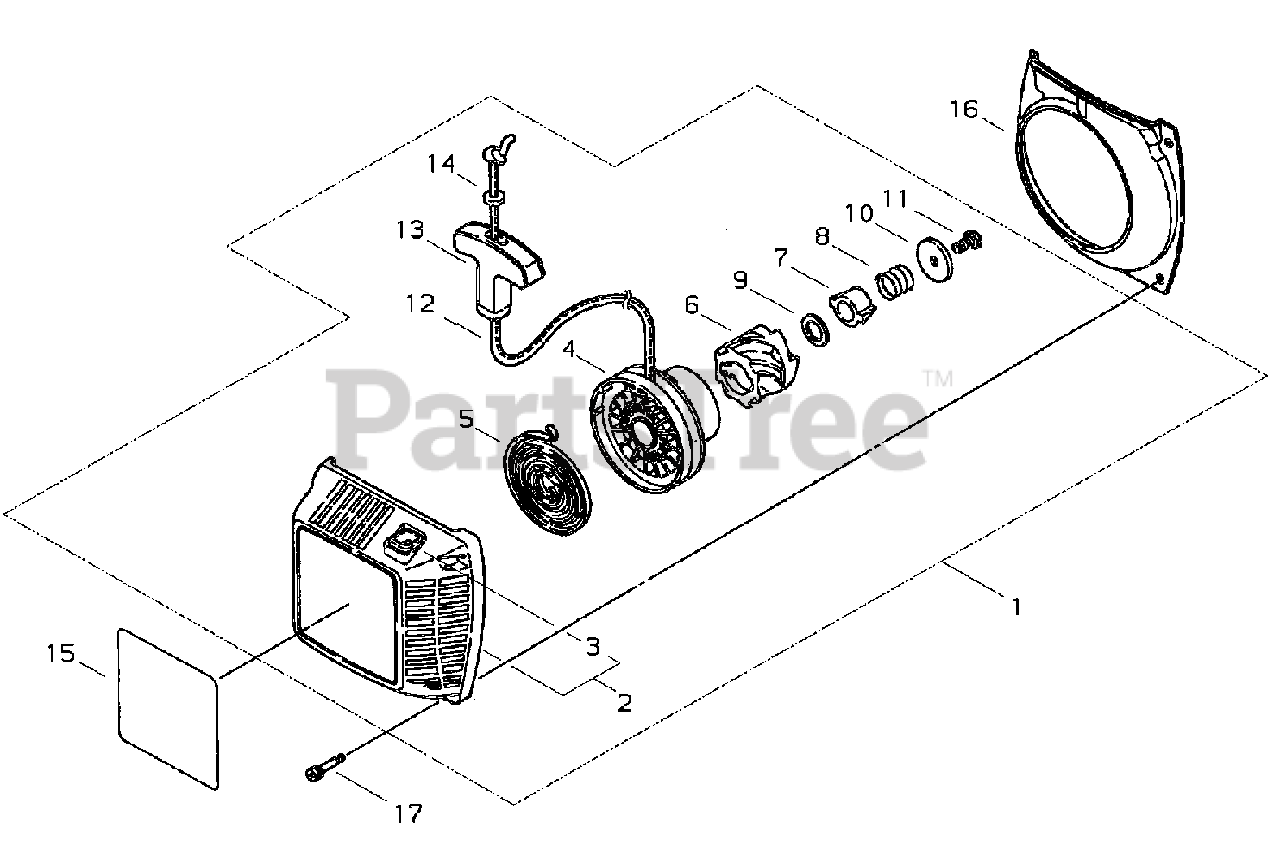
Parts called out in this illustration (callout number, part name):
1	STARTER ASSY, RECOIL
2	CASE ASSY, RECOIL
3	GUIDE, ROPE
4	REEL, ROPE
5	SPRING, RECOIL
6	RATCHET
7	PAWL CATCHER
8	SPRING, FRICTION
9	WASHER, THRUST
10	WASHER
11	SCREW 5
12	ROPE, STARTER
13	GRIP, STARTER
14	RETAINER, ROPE
15	LABEL, TRADE
16	PLATE, AIR
17	BOLT M4×20
